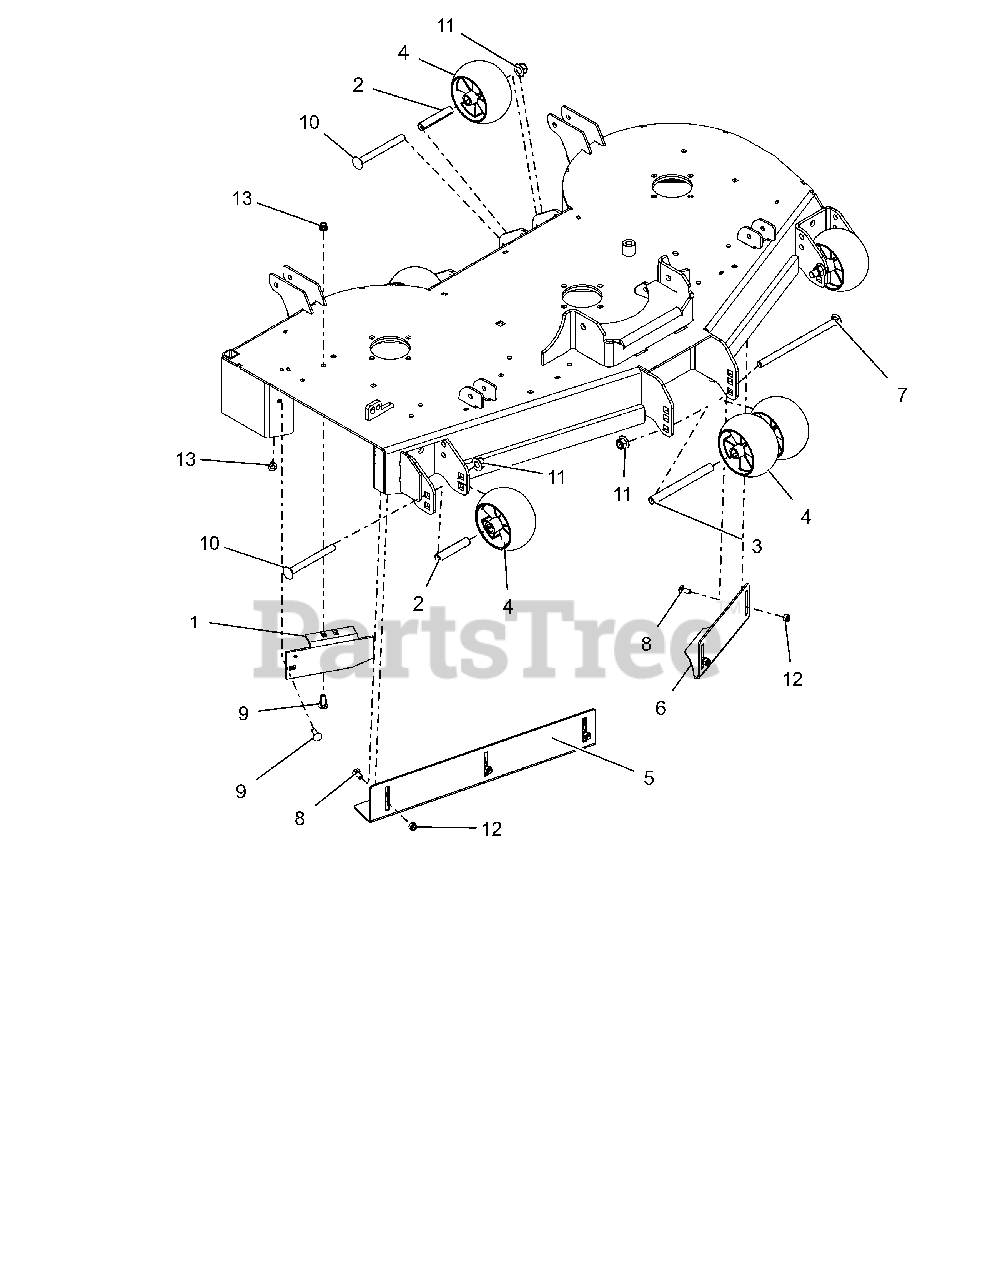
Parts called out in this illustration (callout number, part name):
1	44"-48" SIDE DISCH BAFFLE -RED
2	SPACER, .510X.625X3.35
3	SPACER, .510X.625X6.50
4	ANTI-SCALP WHEEL - 5X3 CTR
5	BAFFLE-48" RH VACUUM
6	BAFFLE-44"/48" LH VACUUM
7	@BLT-RDHDSQNK .50-13X8.50 G5YZ
8	@BLT-RDHDSQNK .31-18X.75 G5YZ
9	@BLT-RDHDSQNK .31-18X1.00 G5YZ
10	BLT-RDHDSQNK .50-13X5.00 GR5YZ
11	@NUT-LK-NYL-FLG .50-13 YWZC
12	@NUT-LK-NYL .312-18 YWZC
13	@NUT-LK-NYL-FLG .31-18 YWZC
